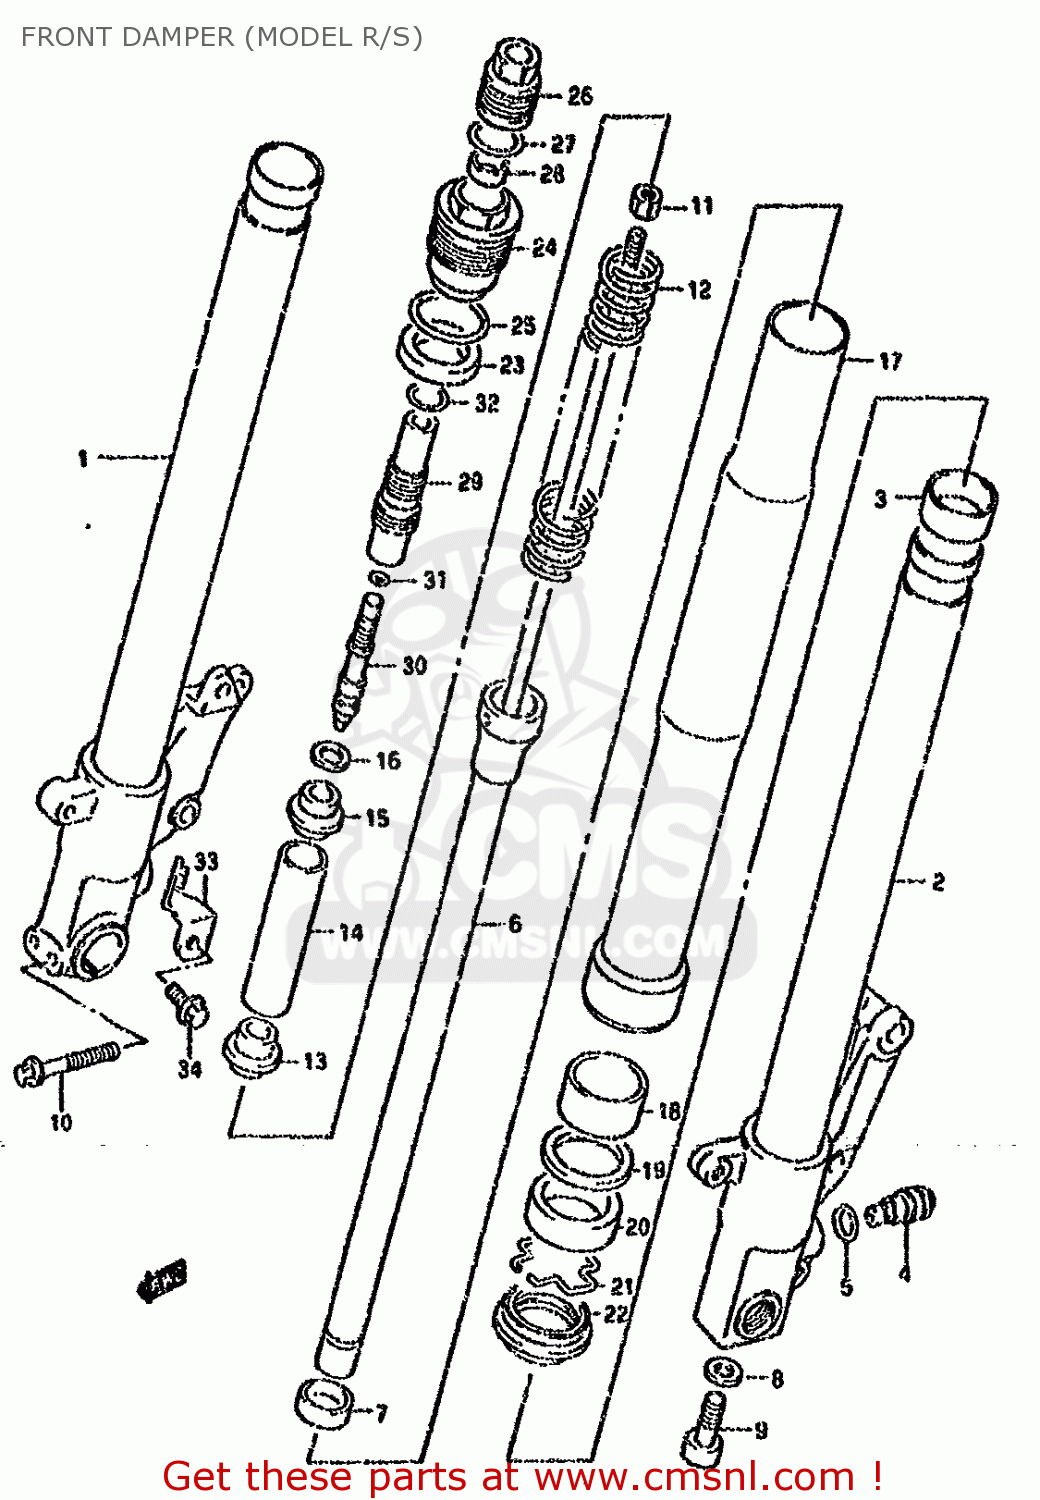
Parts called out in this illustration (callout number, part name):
1	TUBE,INNER,R
2	TUBE,INNER,L
3	BUSH,SLIDE
4	PIECE,ADJUSTER
5	O-RING (D:2.4 ID:13.8)
6	DAMPER,FRONT
7	PLATE,CENTERING
8	WASHER(10X15X1.5)
9	BOLT
10	BOLT
11	NUT
12	SPRING,MAIN
13	JOINT,SPRING
14	SPACER,SPRING
15	GUIDE,SPRING UPR
16	GUIDE,SPRING
17	TUBE,OUTER
18	BUSH,GUIDE
19	SPACER,SEAL
20	SEAL,OIL
21	CIRCLIP,FORK OIL SEAL
22	SEAL,DUST
23	RUBBER,SEAT
24	BOLT,FORK
25	O RING,FORK BOLT
26	ADJUSTER,SPRING
27	O RING
28	PLATE,SPRING ADJUSTER
29	CASE,ADJUSTER
30	PIECE,ADJUSTER
31	O RING(D:1.9,ID:3.8)
32	RING,STOPPER
33	PLATE,FRONT FENDER,LEFT
34	BOLT
